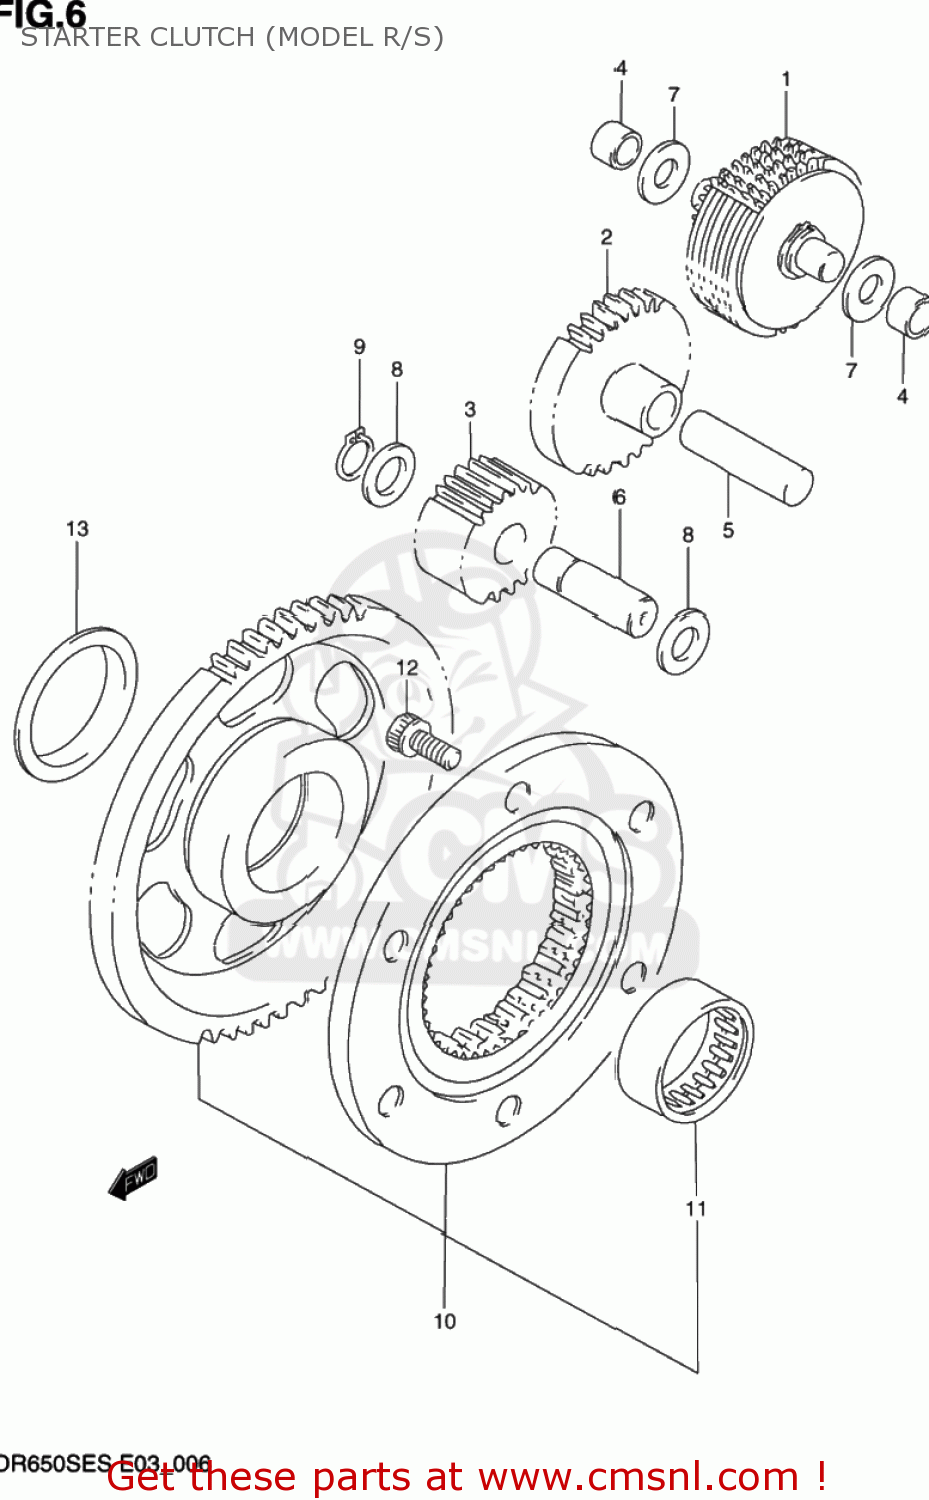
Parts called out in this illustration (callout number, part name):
1	LIMITER ASSEMBLY,STARTER IDLER GEAR
2	GEAR,STARTER IDLE NO.2(NT:27)
3	GEAR,STARTER IDLE NO.3
4	BUSH,LIMITER GEAR SHAFT
5	PIN
6	SHAFT,STARTER IDLE GEAR
7	WASHER
8	SHIM
9	CIRCLIP,12 MM
10	CLUTCH SET,STARTER
11	BEARING(31X39X17.8)
12	BOLT
13	SHIM
